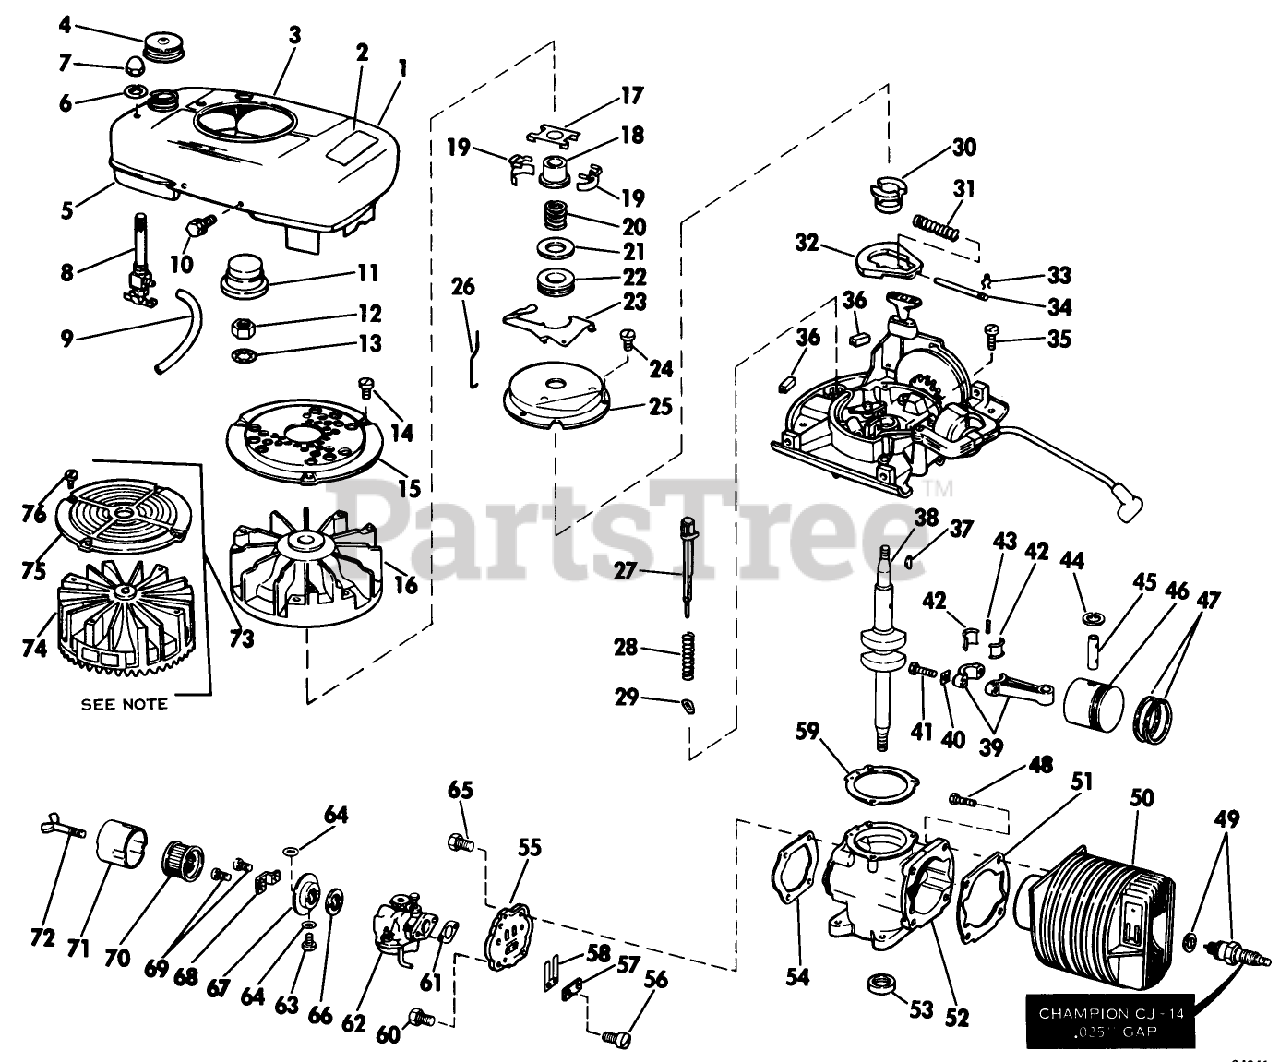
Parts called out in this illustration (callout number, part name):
7	PALNUT S
8	VALVE&SCREEN SM
10	SCREW S
14	SCREW F
18	COLLAR S
22	THRUST COLLAR S
23	LEVER-GOVERNOR S
24	SCREW S
25	DUST COVER S
28	SPRING S
30	SPARK ADV. S
31	SPARK ADV. SPRING S
32	FLYWEIGHT S
33	SPARK ADJ. SPRING
34	PIN,SPARK ADV. S
42	LINER ASM
44	RING-RETAINING
49	Spark Plug Gasket (Champion CJ-14, .025" Gap)
51	GASKET S
55	REED PLATE AY. S
57	PLATE-BACKUP, REED
59	GASKET S
60	SCREW S
61	GASKET S
65	SCREW S
66	GASKET S
73	Flywheel Screen Assy.
74	FLYWHEEL S
76	SCREW F
